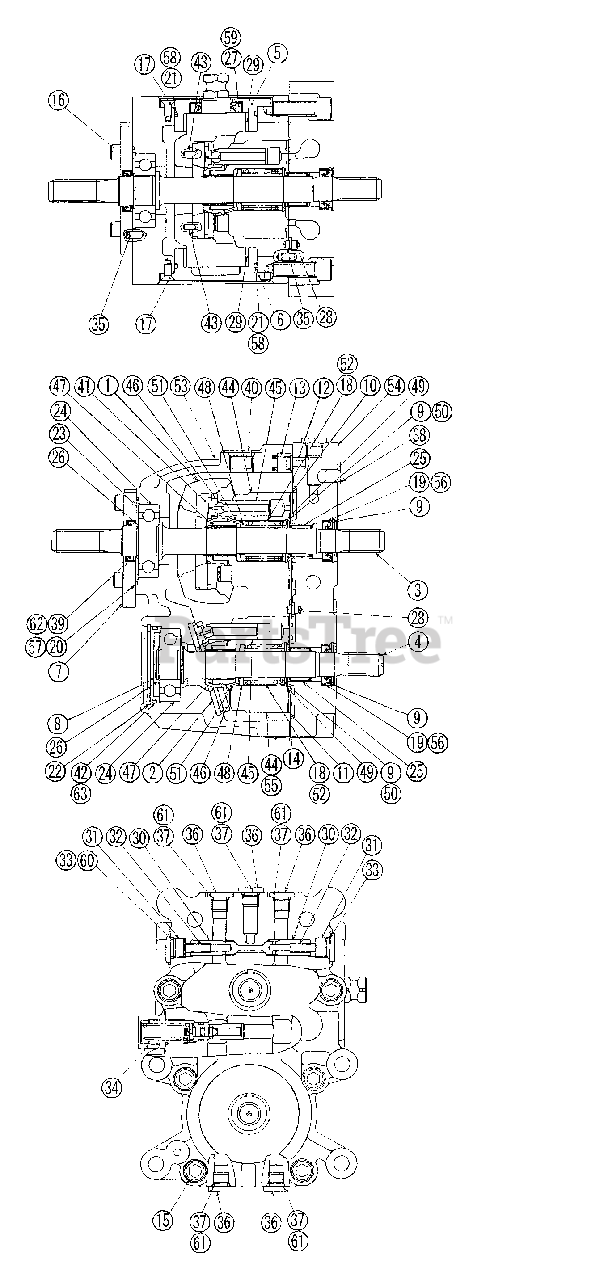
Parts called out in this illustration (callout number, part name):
25	Bearing,Needle
26	C-Ring
44	Cylinder Block
45	Piston
46	Plate,Retainer
47	Holder,Retainer
48	Holder,Spring
49	Holder,Spring
50	C-Ring
51	Pin
52	Spring
53	Case
54	Block
